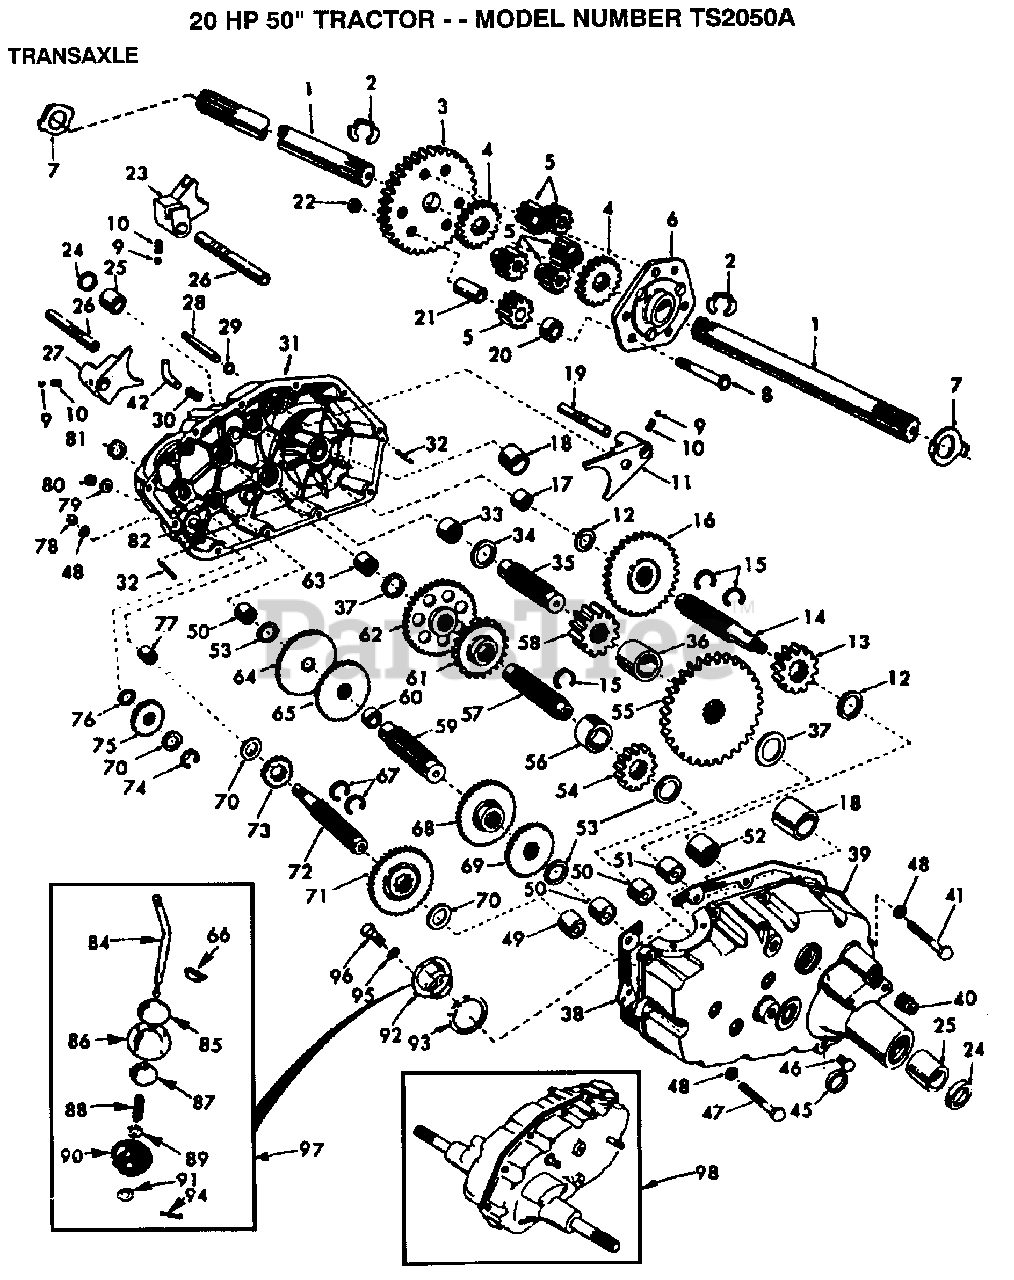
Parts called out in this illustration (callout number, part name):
1	SHAFT.AXLE.T
2	KLIP RING
3	FINAL GEAR T
4	DIFF GEAR T
5	DIFF PINION T
6	DIFF CARRIER T
8	BOLT
11	SHIFT FORK T
12	WASHER .T
13	RED PINION T
14	GEAR SHAFT T
15	SNAP RING T
16	GEAR T
17	"T, BEARING"
18	BEARING
19	SHAFT
20	SPACER T
21	PINION RS
22	GRIPCO NUT
23	FORK T
24	OIL SEAL STD
25	BRNG. T
27	SHIFT FORK T
28	SHIFT SHAFT
29	SEAL T
30	VALVE M
31	GEARCASE RH
32	PIN T
33	NEEDLE BRNG T
34	RACE T
35	GEAR SHAFT T
37	RACE T
38	GASKET
39	GEARCASE LH
40	PLUG PIPE
41	BOLT
42	ELBOW STREET 90
45	SEAL T
47	HEX BOLT
49	"TI, BEARING"
50	NEEDLE BRNG T
51	NEEDLE BRNG T
52	"STD, BEARING"
53	BRNG RACE
54	RED PINION T
55	RED GEAR T
56	PINION SPACER T
57	GEAR SHAFT T
58	FINAL PINION T
59	GEAR SHAFT T
60	SPACER T
61	RED PINION T
62	RED GEAR T
63	RACE T
64	LOW SPEED GEA T
65	REVERSE GEAR T
66	KEY T
67	RING STD
68	INTERMED GEAR T
70	"T, BEARING"
71	CLUSTER GEAR T
72	INPUT SHAFT T
73	LO SPEED PINION T
75	IDLER GEAR T
76	WASHER T
77	BRNG T
78	NUT.HEX.5/16-18
79	WASHER T
80	NUT
81	SEAL STD
84	GEAR SHIFT LVR T
85	CAP T
86	COVER AND PIN T
87	GUIDE BALL T
88	SPRING TI
89	WASHER
90	SEAL T
91	WASHER
92	GEAR SHIFT GA T
93	GASKET T
94	COTTER PIN
95	LOCKWASHER
96	BOLT
97	GEAR SHFT LVR T
